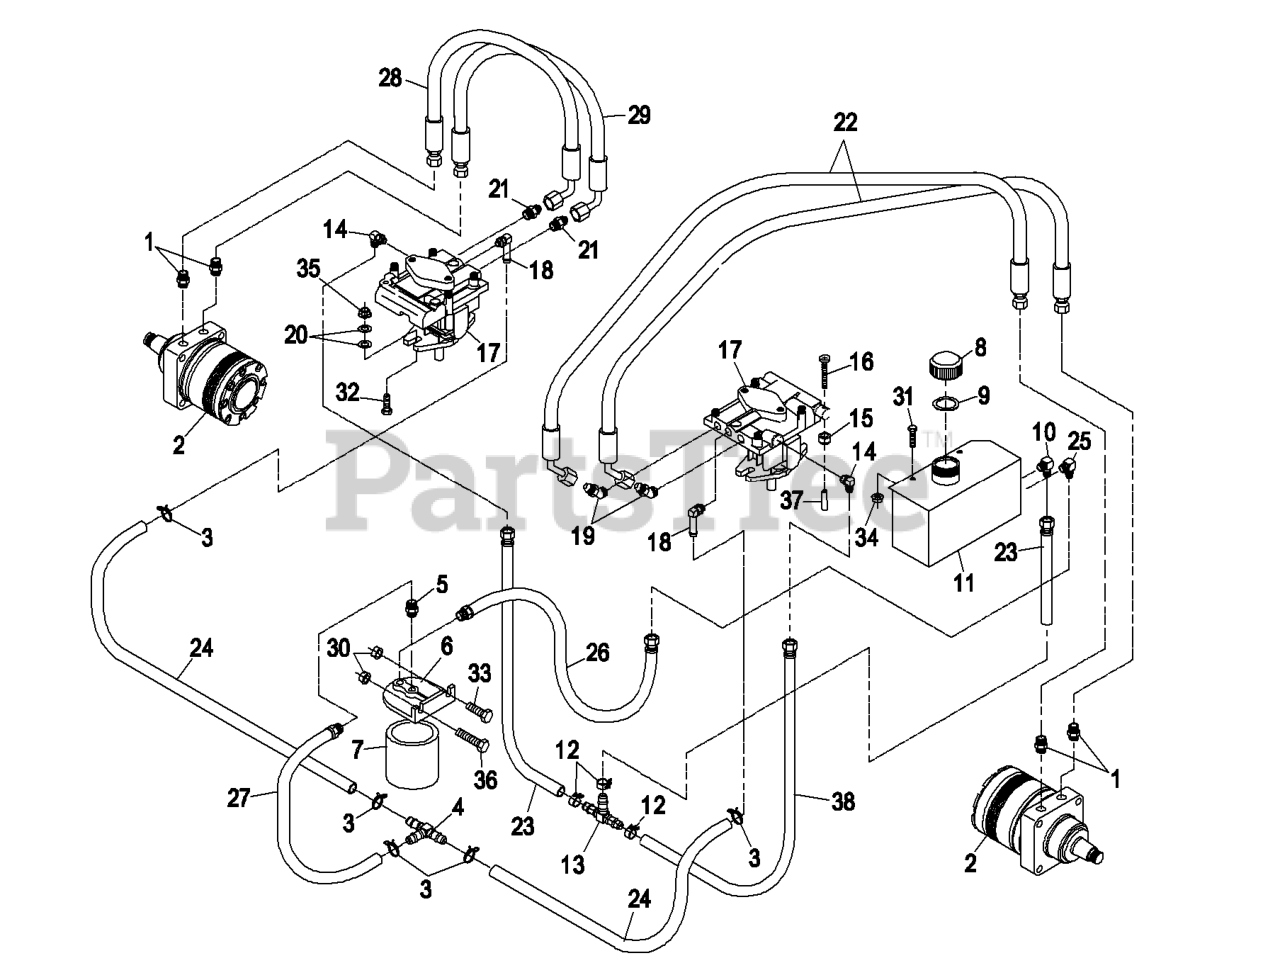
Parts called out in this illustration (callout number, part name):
1	FITTING-STRAIGHT
2	HYD MOTOR ASM
3	CLAMP-HOSE
4	FITTING-TEE, HOSE
5	FITTING-STRAIGHT
9	GASKET-CAP, TANK
10	FITTING-ELBOW
12	CLAMP-HOSE
13	FITTING-TEE, HOSE
14	FITTING-90 DEG
18	FITTING
19	FITTING-HYD, 45 DEG
21	FITTING-STRAIGHT
22	HOSE,HIGH PRESSURE
23	ASM,HOSE CASE DRAIN
24	HOSE,LO PRESSURE
25	FITTING-ELBOW
26	ASM,HOSE LO PRESSURE
27	ASM,HOSE CHARGE LINE
29	HOSE-PRESSURE, HIGH
37	GRIP-VALVE, DUMP
38	HOSE ASM
